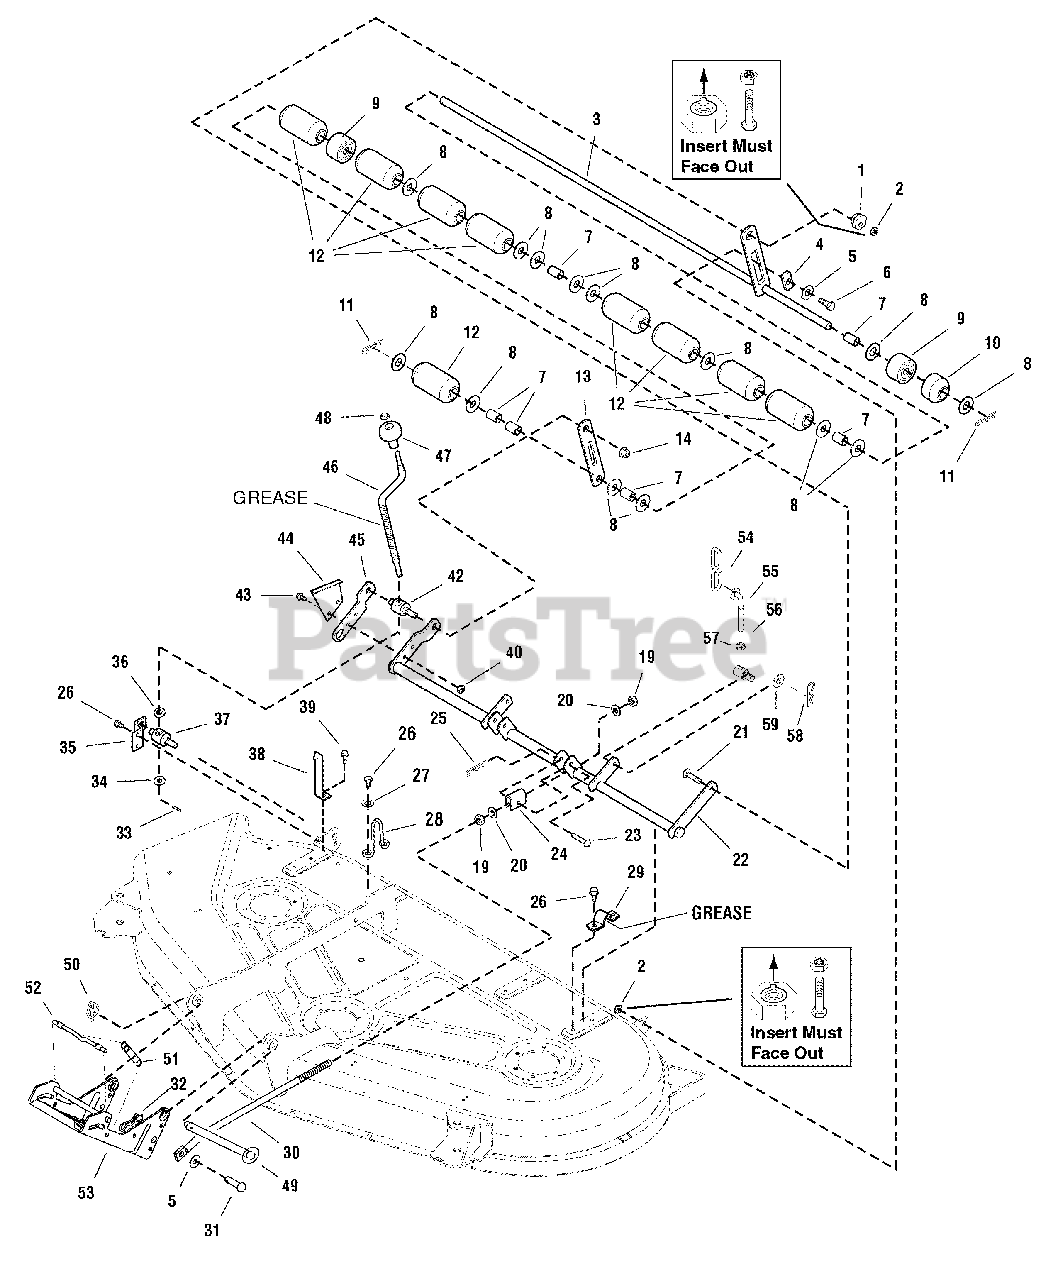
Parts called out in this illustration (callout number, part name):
1	NUT, Hex Adjusting, .99 DIA .687
2	NUT, Hex Aluminum Insert Lock, 3/8-16
3	SHAFT & BAR ASSEMBLY, Roller
5	WASHER, 1/2
6	BOLT, Shoulder, 3/8-16 X 1.34
9	ROLLER, 1 x 2-3/4 x 2, Black
10	ROLLER, Half Rounded
11	PIN, Cotter, 1/8 x 1-1/2, Black
12	ROLLER, with Bushings, Full
14	NUT, Hex Flange, 1/2-13
19	NUT, Hex, 5/8-11
20	WASHER, 5/8
21	CARRIAGE BOLT, 3/8-16 x 1-1/2
22	ASSEMBLY, Rocker Shaft
23	PIN, Round Head, 3/8 x 2
24	TRUNNION
25	CLIP, Hair Pin
26	CAPSCREW, Hex Washer Head, Taptite, 5/16-18 x 3/4
27	WASHER, 5/8
28	UP-STOP, Wire
29	STRAP
30	ROD, 5/8 x 29-5/8 Long
31	PIN, Yoke, 1/2
32	PIN, Bow Tie
34	WASHER, Detent, 1/2
35	SUPPORT, Trunnion
36	WASHER, 1/2
38	INDICATOR, Height of Cut
39	SCREW, Taptight 5/16-18 x 1 1/14
40	NUT, Hex, 5/16-18 Whiz Lock
42	TRUNNION, Threaded
43	CAPSCREW, Hex Head, 5/16-18 x 1-1/4
44	BRACKET, Height of Cut
46	CRANK, Height Adjust
47	KNOB, Spinner
48	PUSHNUT, 3/8
49	ASSEMBLY, Hitch Pin
53	ASSEMBLY, Hitch
54	CHAIN 2-Link
55	ROD, Height Adjust
56	NUT, Hex Jam
58	CLIP, Hair Pin
59	WASHER, 3/8
